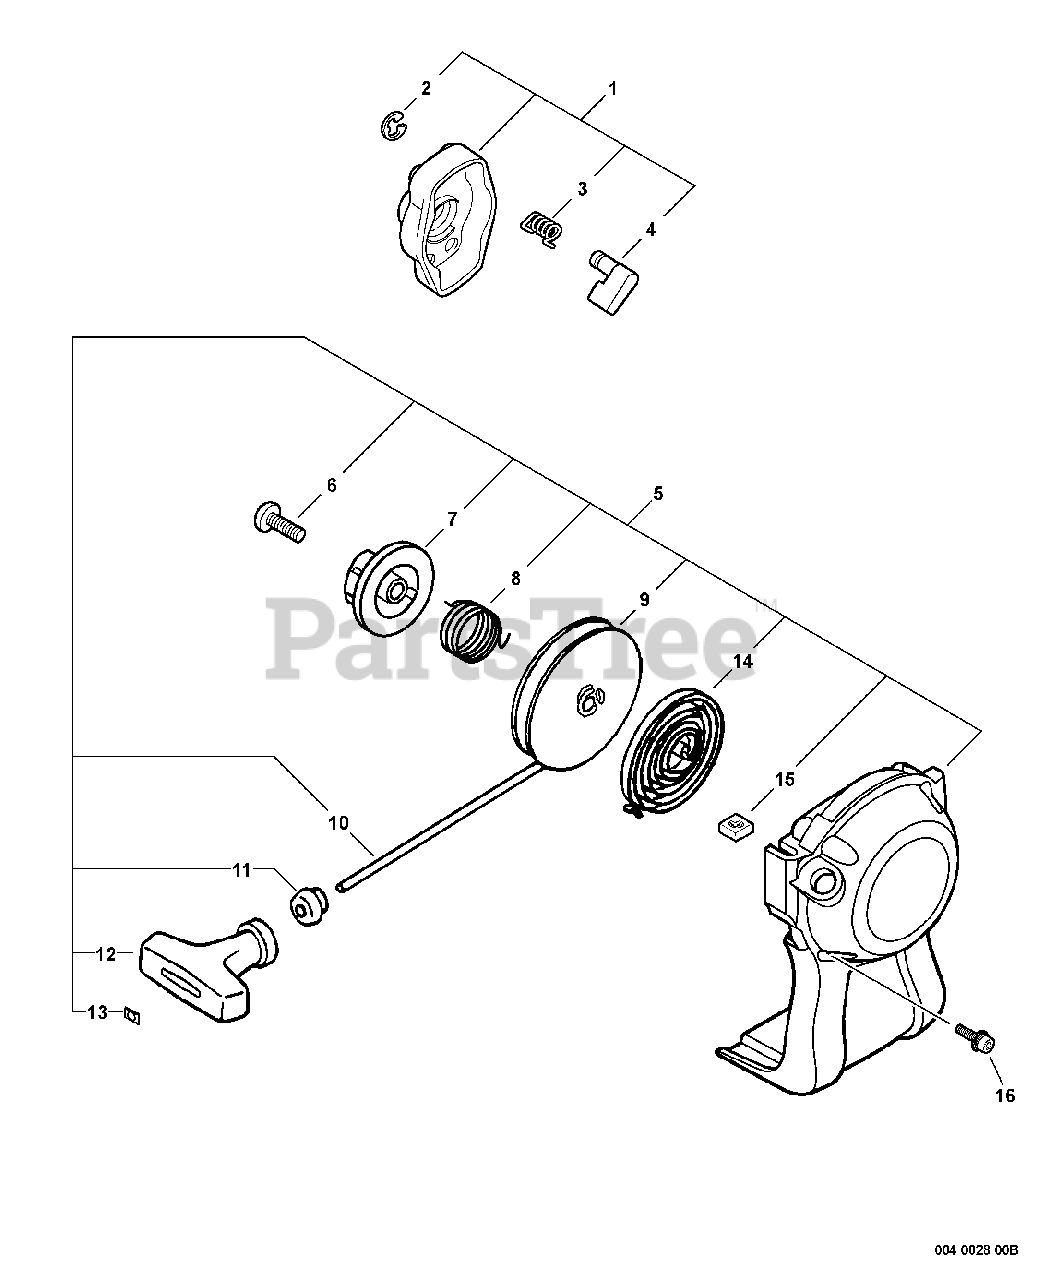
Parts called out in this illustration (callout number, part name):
1	PAWL ASSY, STARTER
2	E-RING 4
3	SPRING, RETURN
4	PAWL, STARTER
5	STARTER ASSY
6	SCREW
7	PLATE, CAM (NLA SEE PB 15-06)
8	SPRING, TORSION
9	REEL, ROPE
10	ROPE, STARTER 3×700
11	GUIDE, ROPE
12	GRIP, STARTER
13	RETAINER, ROPE
14	SPRING, RECOIL
15	NUT M5
16	BOLT 4×16
